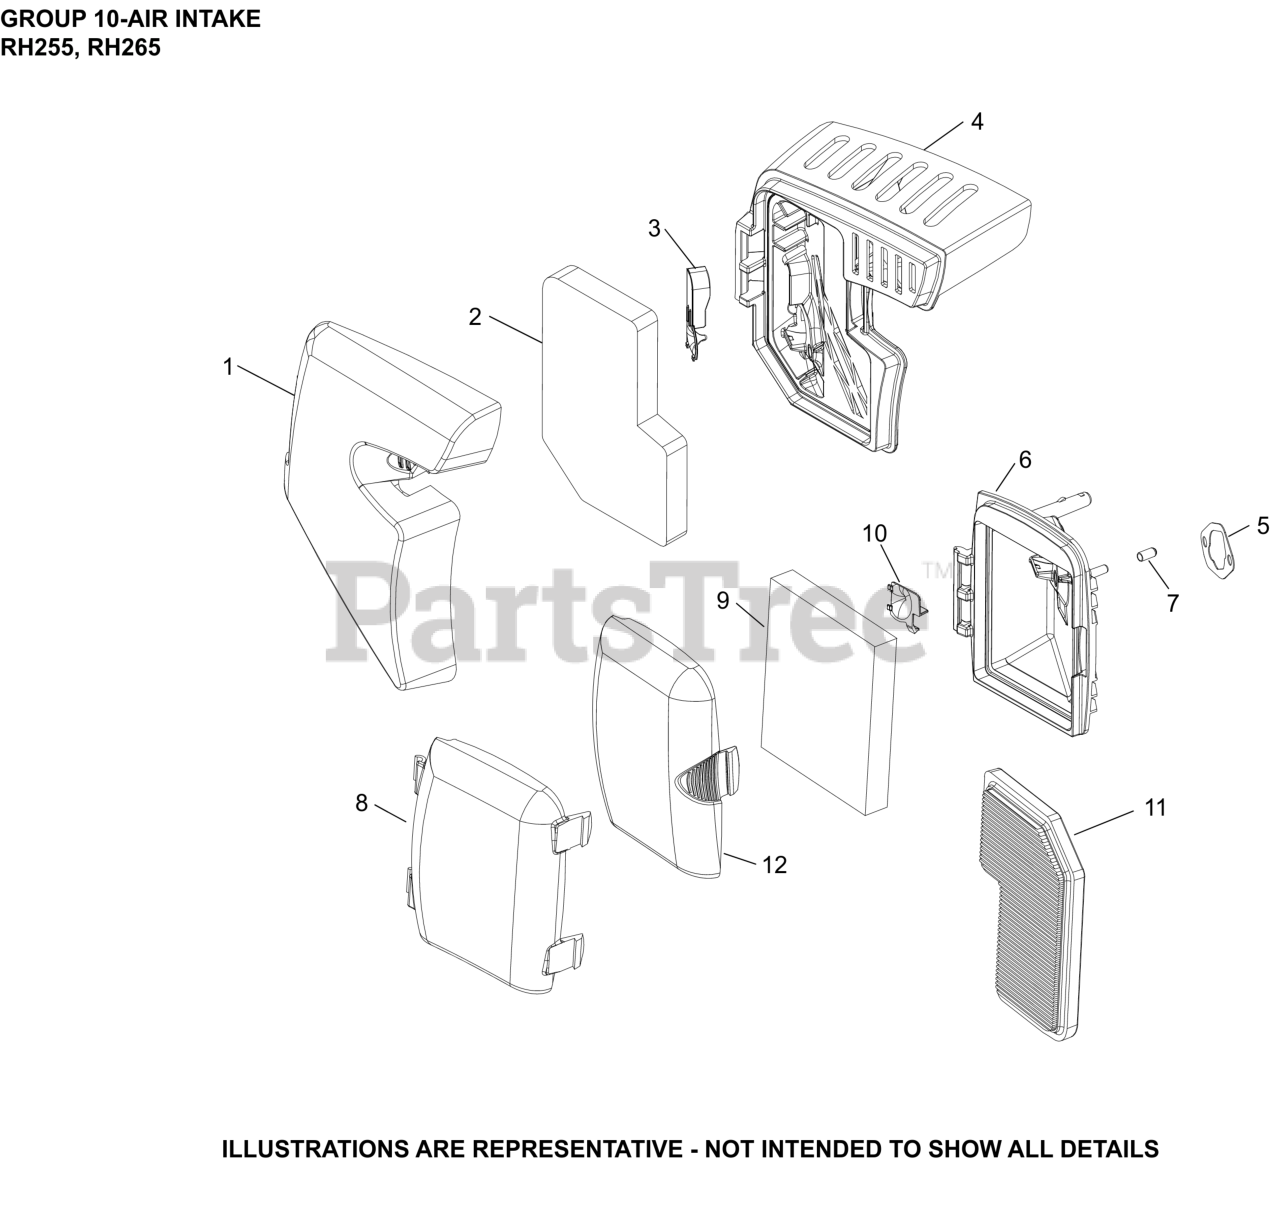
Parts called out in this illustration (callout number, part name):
1	COVER, AIR CLEANER
2	ELEMENT, AIR FILTER - FOAM
3	COVER, SPIT CUP
4	BASE, AIR CLEANER
5	GASKET, CARBURETOR A/C BASE
